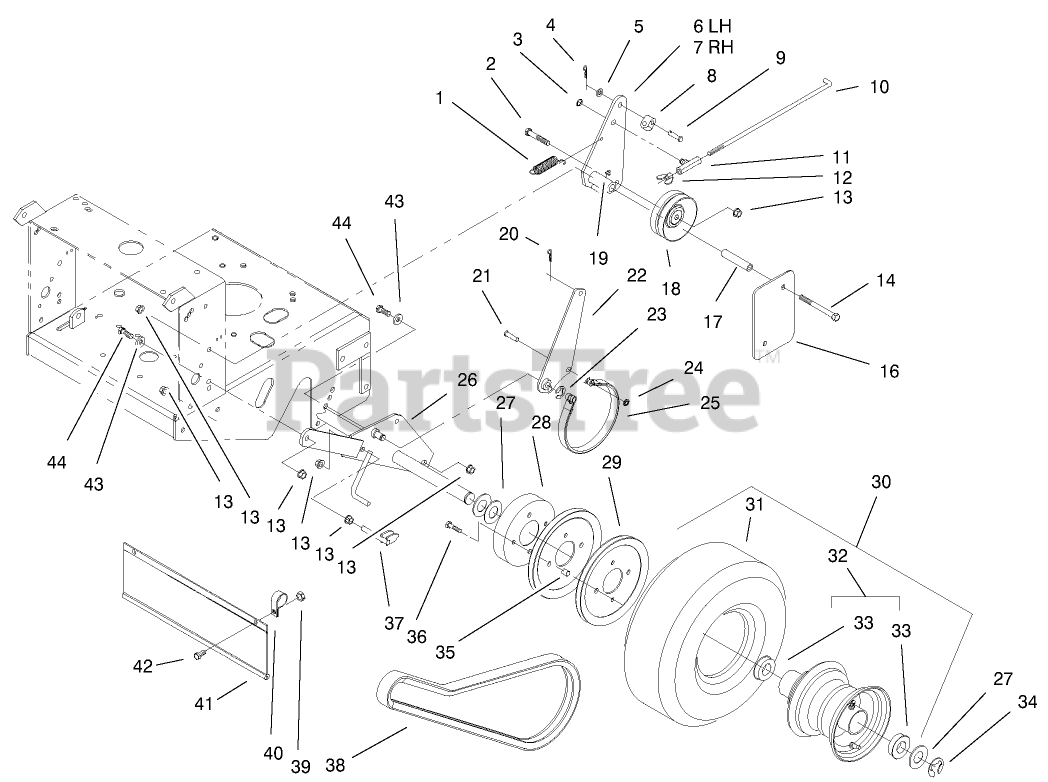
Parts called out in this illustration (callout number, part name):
1	Spring-Extension
2	SCREW-HH
3	Ring
4	PIN-COTTER
5	WASHER-PLAIN
6	Idler Arm ASM LH
7	Idler Arm ASM RH
8	FITTING-ROD
9	PIN-CLEVIS
10	Brake Rod
11	Swivel
12	Wingnut
13	NUT-HHF, WHIZ
14	SCREW-HH
16	Shield
17	Idler
18	Idler-Wheel Drive
19	FITTING-GREASE
20	PIN-COTTER
21	Pin
22	Brake Arm ASM
23	Ring-Snap
24	Nut
25	Band-Brake
26	Axle ASM
27	Spacer
27	Spacer-18 GA
28	Drum-Brake
29	Sheave
30	Wheel/Tire ASM
31	Tire
32	Rim Only w/Bearings
33	Bearing
34	Ring,Snap E
35	Spacer
36	Bolt-Whiz Lock
37	Scraper
38	Belt-Drive
39	NUT-LOCK, NI
40	CLAMP-R
41	Shield-Trailing
42	SCREW-HH
43	Washer
44	SCREW-HH
